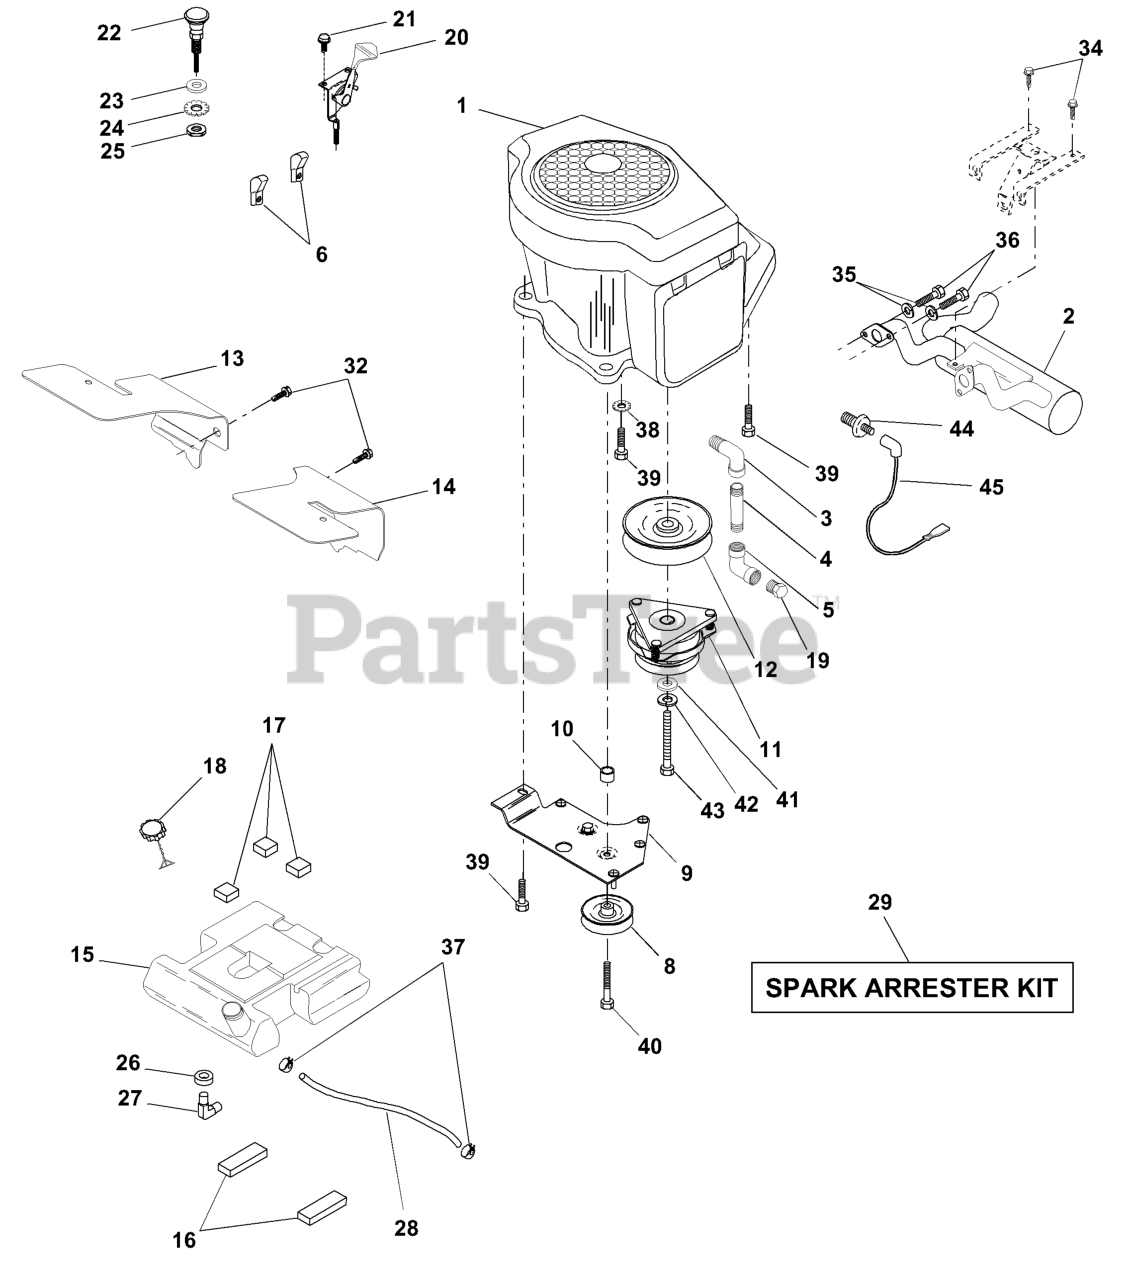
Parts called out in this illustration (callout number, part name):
1	Engine Kohler,
2	MUFFLER
3	STREET ELBOW LT NLA
4	Nipple Pipe 3/8 NPT X 3 - 1/2
5	ELBOW
8	RP.IDLER GROOVED
9	STOP KEEPER
11	CLUTCH.ELECT.CVX.105 FT/LB.
12	PULLEY, ENGINE
13	AIR BAFFLE
14	AIR BAFFLE RH
15	FUEL TANK
16	PAD IDLER TI
17	PAD-SPACER LT
18	FUEL CAP
19	PLUG T
20	THROTTLE CONTROL
21	SCREW LT
22	CONTROL.CHOKE.51.00.BLK.W/BEND
23	WASHER
24	LOCKWASHER
25	NUT
26	BUSHING OUTLET T
27	STEM FUEL TANK
28	HOSE
29	SPARK ARRESTOR
32	Screw Thdrol 5/16 - 18 X 1/2
34	SCREW
35	WASHER.LOCK.HVY.HLCL.SPR.5/16
36	Screw Hex 5/16 - 16 UNC X 3/4
37	HOSE CLAMP
38	LOCKWASHER
39	SCREW LT
40	Screw Thdrol 3/8 - 16 X 3 - 1/4
42	LOCKWASHER
43	BOLT
44	SWITCH, OIL PRESSURE
